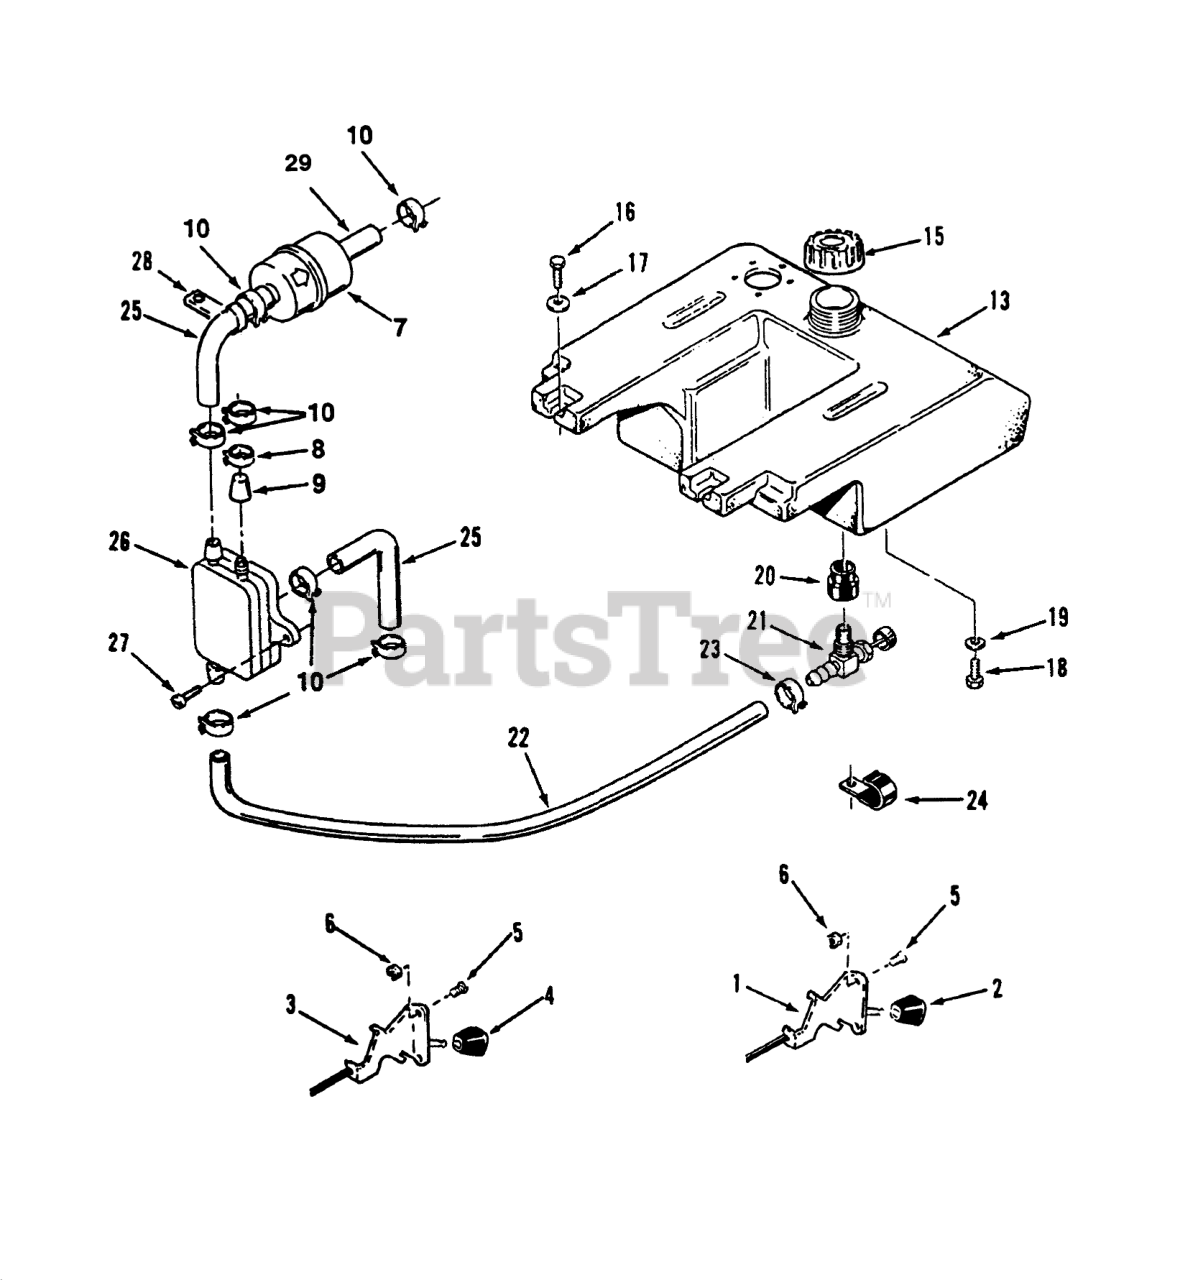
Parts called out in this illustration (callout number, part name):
1	CONTROL-THROTTLE
2	KNOB-CONTROL
3	CONTROL-CHOKE
4	KNOB-CONTROL
5	Screw
6	Nut
7	Filter-Fuel
8	CLAMP
9	CAP-FUEL OUTLET
10	CLAMP-HOSE
13	Tank-Fuel (Includes Items 20 & 21)
15	GAS CAP ASM
16	Bolt
17	WASHER-FLAT
18	SCREW-HH
19	10-24 X 3/4 FIL HD MS
20	BUSHING
21	VALVE-FUEL
22	Line-Fuel 53"
23	Clamp
24	Clamp
25	Hose
26	PUMP-FUEL
27	SCREW-TAPPING PAN HD
28	Clip
29	FUEL HOSE
